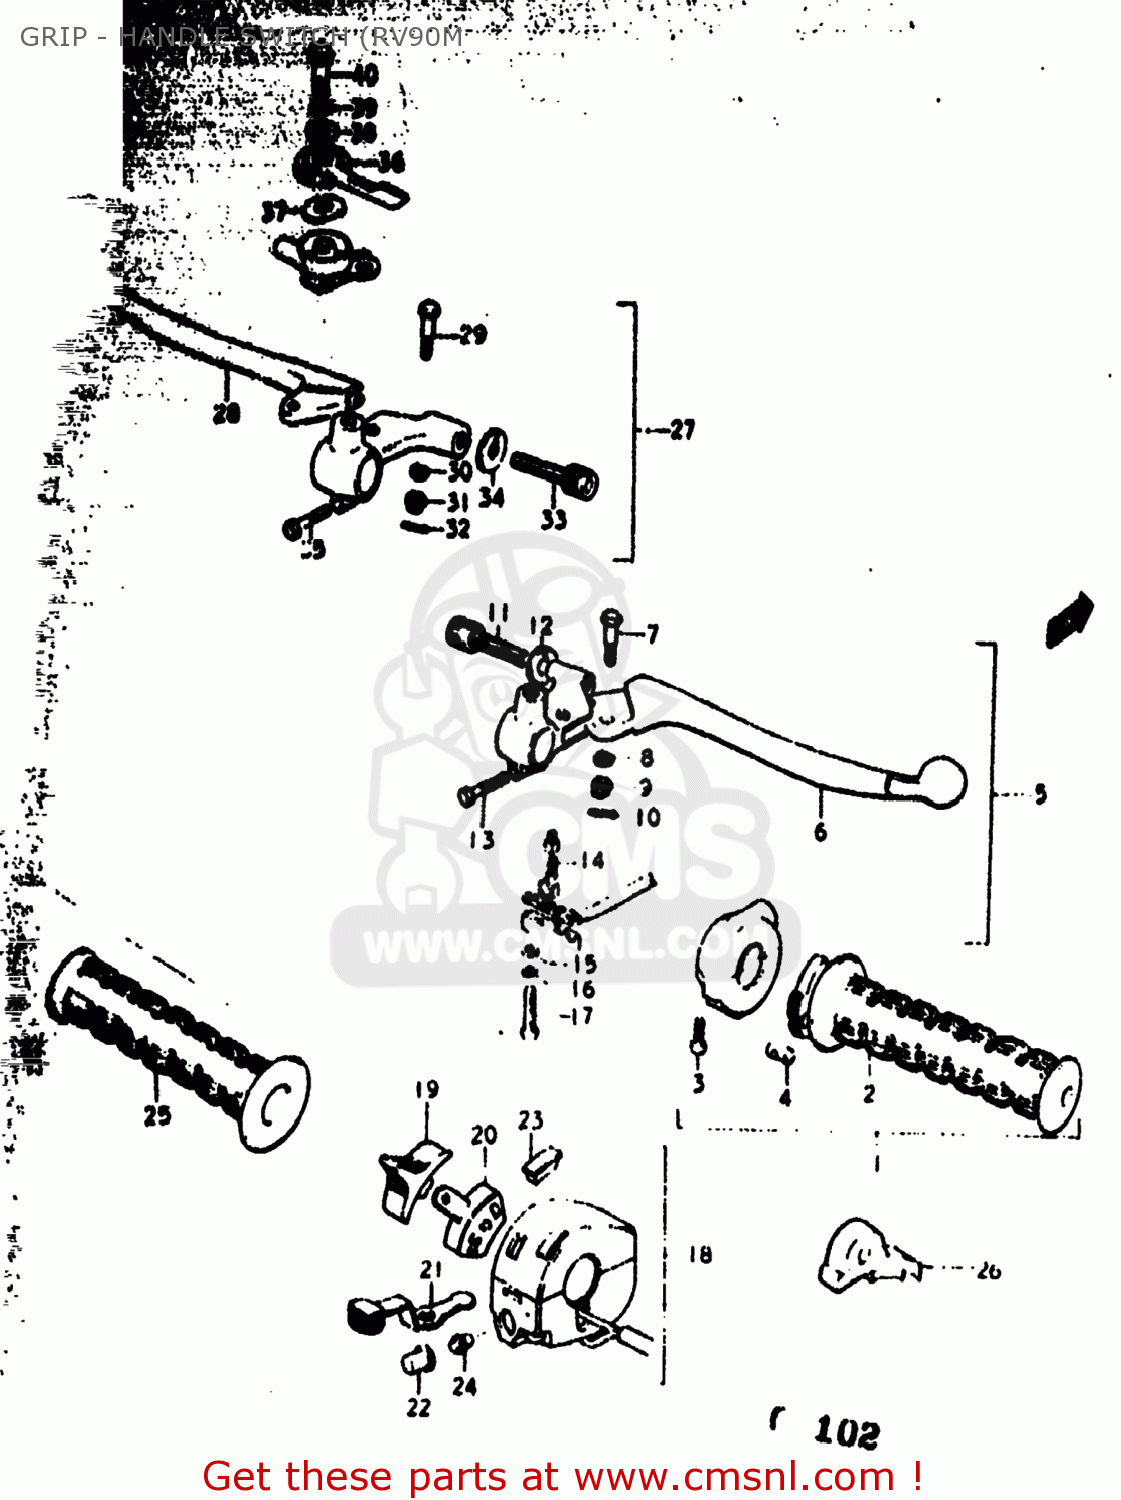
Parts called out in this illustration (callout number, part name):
1	GRIP ASSEMBLY,THROTTLE
2	GRIP,THROTTLE
3	SCREW
4	PIECE,THROTTLE END
5	LEVER/SWITCH ASSEMBLY,BRAKE
6	LEVER ASSEMBLY,ADJUST
7	BOLT,LEVER
8	LOCK WASHER
9	NUT,LEVER FITTNG
10	COTTER PIN
11	ADJUSTER,CABLE
12	NUT,CABLE ADJUSTER
13	BOLT
14	SPRING
15	WASHER
16	LOCK WASHER
17	SCREW
18	SWITCH ASSEMBLY,HANDLE
19	KNOB,HANDLE SWITCH,UPPER
20	SLIDING BLOCK, DIMMER SWITCH
21	KNOB,HANDLE SWITCH
22	BUTTON, HORN
24	PLATE,HORN BUTTON
25	GRIP
27	LEVER ASSEMBLY
28	LEVER,CLUTCH
29	BOLT,LEVER PIVOT
30	LOCK WASHER
31	NUT,LEVER FITTNG
32	COTTER PIN
33	ADJUSTER,CABLE
34	NUT,CABLE ADJUSTER
35	BOLT
36	LEVER
37	WASHER,ADJUSTER
38	WASHER,STARTER LEVER
39	LOCK WASHER
40	BOLT
